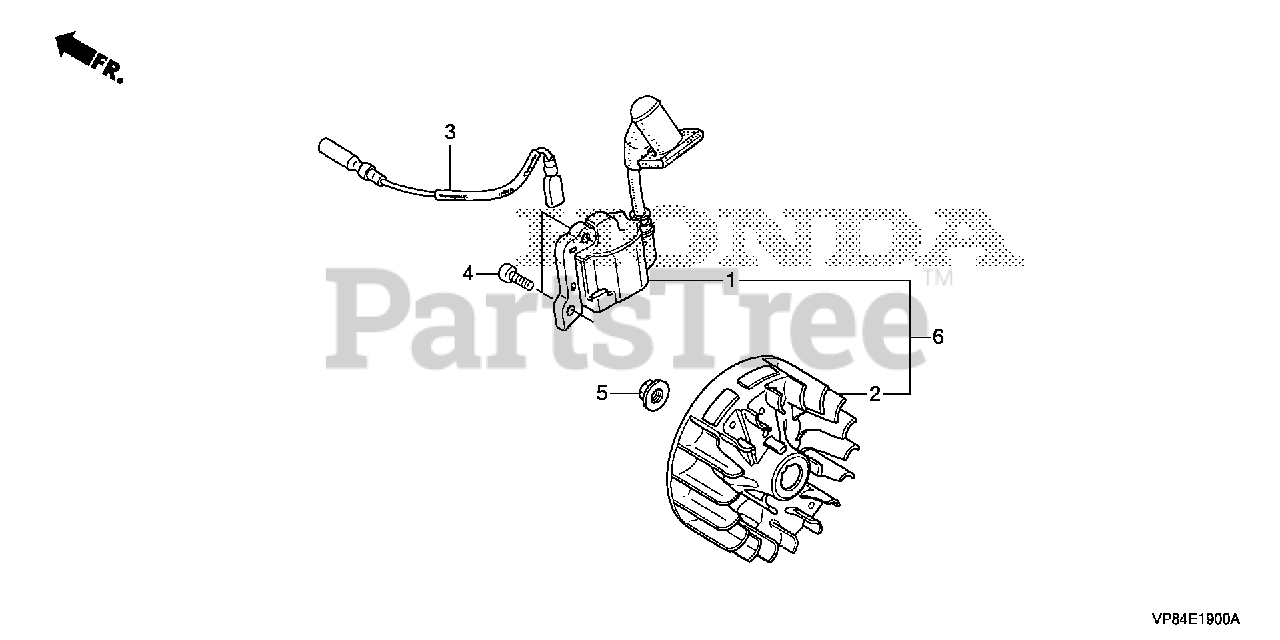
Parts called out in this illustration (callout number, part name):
1	COIL ASSY., IGNITION
2	FLYWHEEL
3	WIRE, STOP SWITCH
4	BOLT, SOCKET (4X14)
5	NUT, FLANGE (7MM)
6	IGNITION COIL & FLYWHEEL KIT
